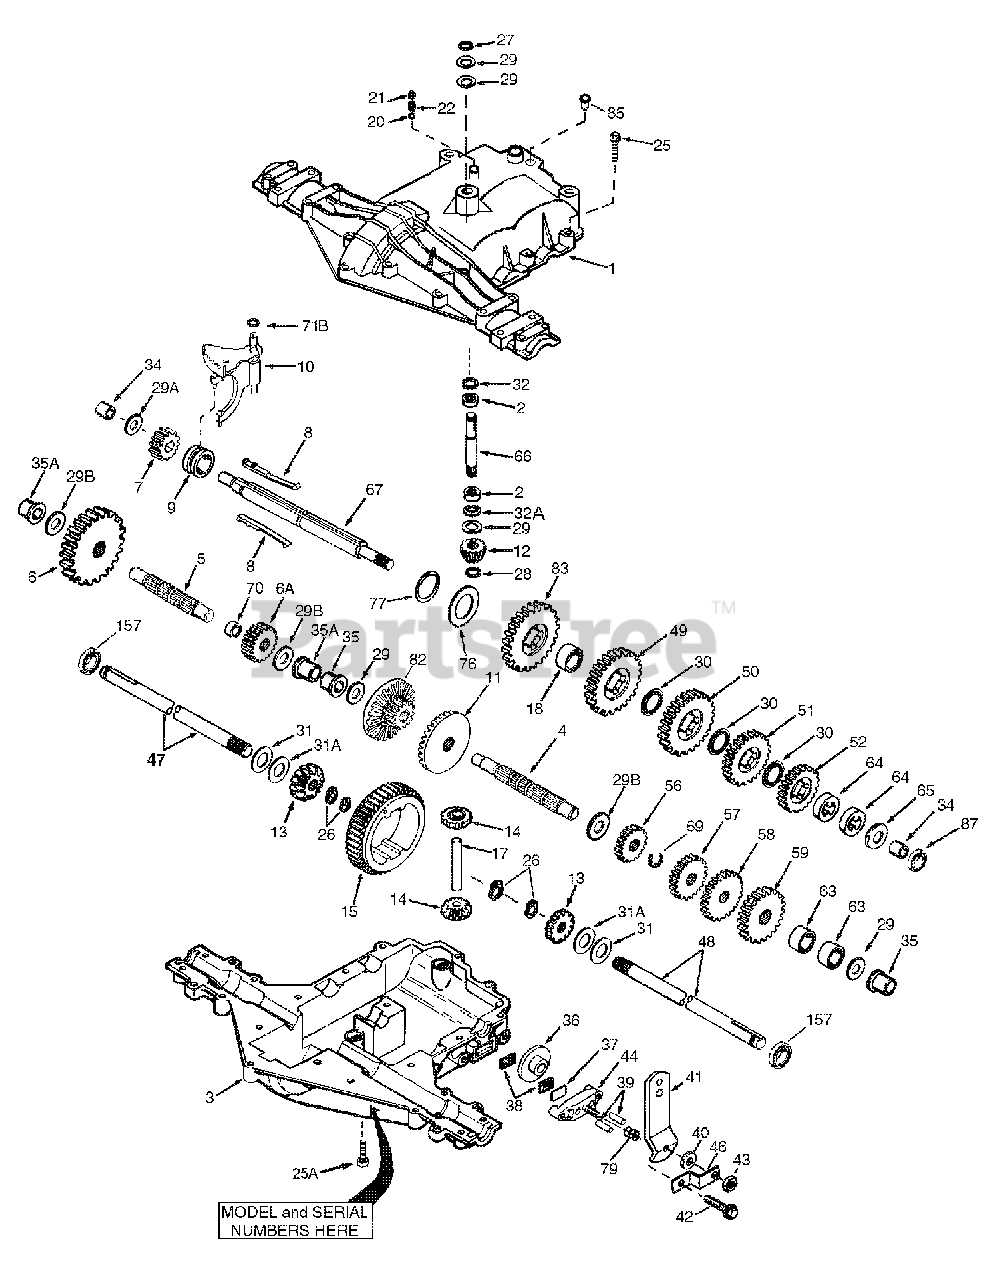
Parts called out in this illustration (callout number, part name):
1	Transaxle Cover
2	Needle Bearing (1/2" long)
3	Transaxle Case
4	Countershaft
5	Output Shaft
6	Spur Gear (38T-PM/SER)
6A	Spur Gear (15T-PM/SER)
7	Spur Gear (11T-PM/SER)
8	Shift Key Set (Qty. 2)
9	Shift Collar
10	Shift Rod & Fork Assembly
11	Bevel Gear (30T-PM)
12	Input Bevel Pinion (13T-PM)
13	Bevel Gear 13T (Incl. ref. 13 & 14) Complete Set of 4-gears
14	Bevel Gear 13T (Incl. ref. 13 & 14) Complete Set of 4-gears
15	Ring Gear (43T)
17	Drive Pin
18	Spacer (1.130" x .695")
20	Ball (Stainless Steel 5/16" dia.)
21	Screw, 3/8-16 x 3/8"
22	Spring
25	Screw, 1/4-20 x 1-1/4"
25A	Screw, 1/4-20 x 1-3/8"
26	Retaining Ring-package of 2
27	Retaining Ring
28	Retaining Ring
29	Washer .627" ID .031"
29A	Thrust Washer (.563" ID x .031")
29B	Thrust Washer (.762" ID X .031")
30	Shift Washer (Cupped)
31	Washer .750" ID .56"
31A	Washer .750" ID .062
32	Oil Seal 5/8"
32A	O Ring (.823" OD)
34	Bushing (.563")
35	Flanged Bushing (.625" ID)
35A	Flanged Bushing (.751" ID)
36	Brake Disk
37	Brake Pad Plate
38	BRAKE PAD KIT (1 PKG = 2 PADS )
39	Dowel Pin .3125" x .750"
40	Washer .312" ID .059"
41	Brake Lever
42	Screw 1/4-20 x 1-3/8"
43	Lock Nut 5/16-24
44	Brake Pad Holder
46	Bracket
47	Axle (10.719" long) (Incl. 26)
48	Axle (15.312" long) (Incl. 26)
49	Spur Gear (27T-PM/IC)
50	Spur Gear (22T-PM/IC)
51	Spur Gear (19T-PM/IC)
52	Spur Gear (16T-PM/IC)
56	Spur Gear (13T-PM/SER)
57	Spur Gear (18T-PM/SER)
58	Spur Gear (21T-PM/SER)
59	Spur Gear (24T-PM/SER)
63	Countershaft Spacer 1-1/8" x 3/8''
64	Brake Shaft Spacer 1-3/8" x 3/8''
65	Washer .563" ID .062
66	Input Shaft
67	Brake Shaft
69	Retaining Ring (.75" x .042")
70	Spacer (.890")
71B	O-Ring
76	Flat Washer (1.128" ID x .058")
77	Retaining Ring (1.125" x .050")
79	Spring
82	Bevel (30T) & Spur Gear
83	Spur Gear (27T-PM/IC)
85	Oil Fill Plug
87	Oil Seal 9/16" ID
157	Oil Seal 3/4" ID
